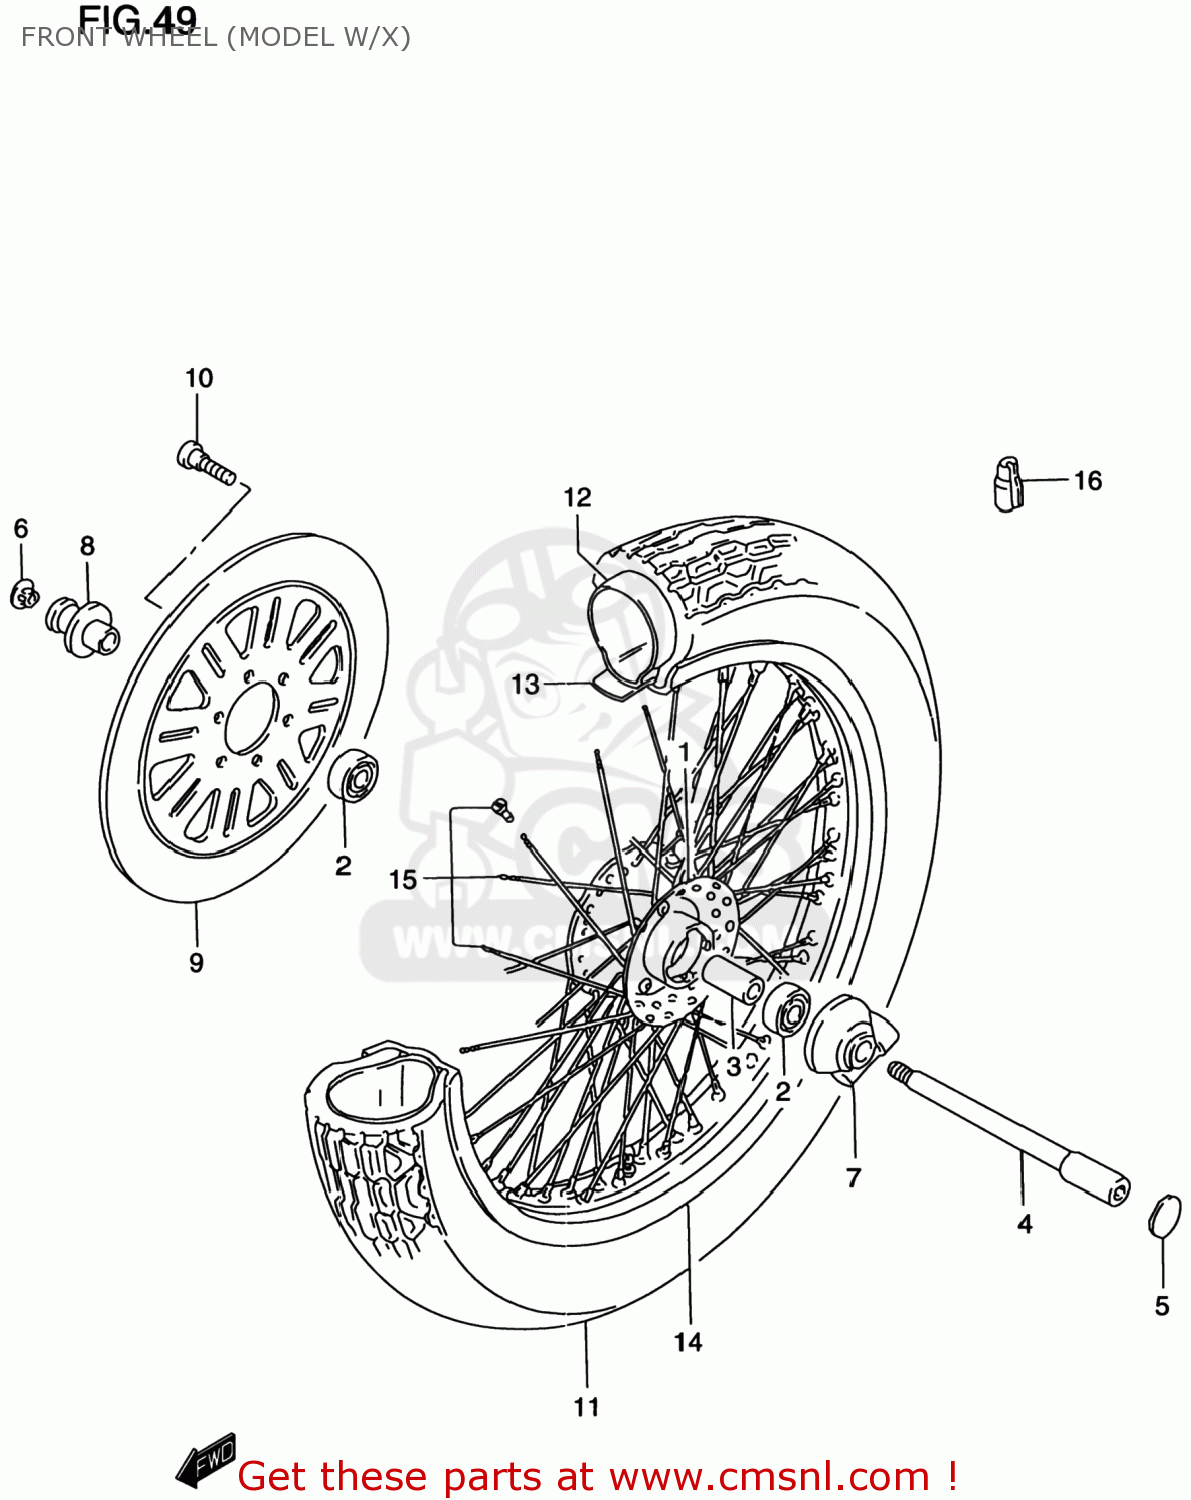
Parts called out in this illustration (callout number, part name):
1	HUB ASSY,FR
2	BEARING
3	SPACER(15.3X21.7X65)
4	AXLE,FR
5	CAP,FR AXLE
6	CAP,FR AXLE
7	BOX ASSY,SPEEDOMETER
8	SPACER,FR AXLE
9	DISC,FR BRAKE
10	BOLT 8X33
11	TIRE,FR(80/90 21 48H)
12	TUBE
13	PROTECTOR,WHEEL INNER
14	RIM,FR WHEEL(21X2.15 AL)
15	SPOKE SET,FR WHEEL
16	BALANCER,WHEEL
